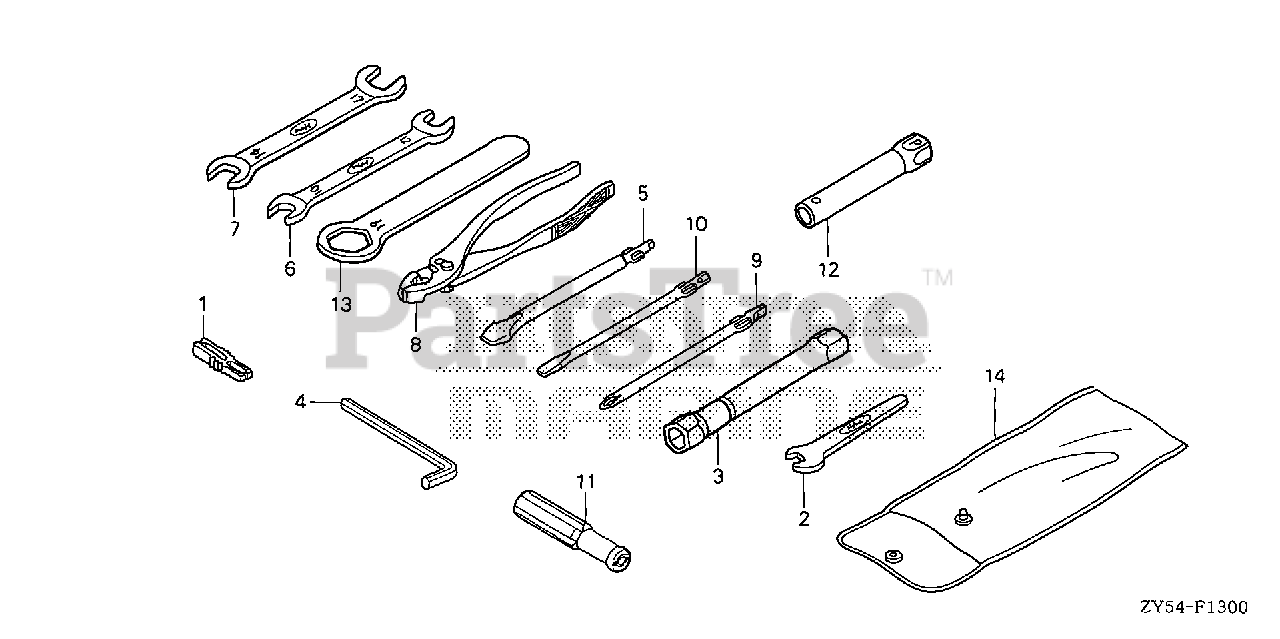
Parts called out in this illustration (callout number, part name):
1	PULLER, MINI FUSE (SUMITOMO)
2	SPANNER (8MM) (NOT AVAILABLE)
3	WRENCH, PLUG
4	WRENCH, HEX. (6MM)
5	SCREWDRIVER, CHECK BOLT
6	SPANNER (10X12)
7	SPANNER (14X17)
8	PLIERS (135) (KOWA)
8	PLIERS (135)
9	DRIVER 1, PLUS SCREW (NO.2)
10	DRIVER 3, MINUS SCREW (NO.2)
11	GRIP, SCREW DRIVER
12	WRENCH, BOX (P16X17)
13	WRENCH, EYE (19MM)
14	BAG, TOOL (230MM)
